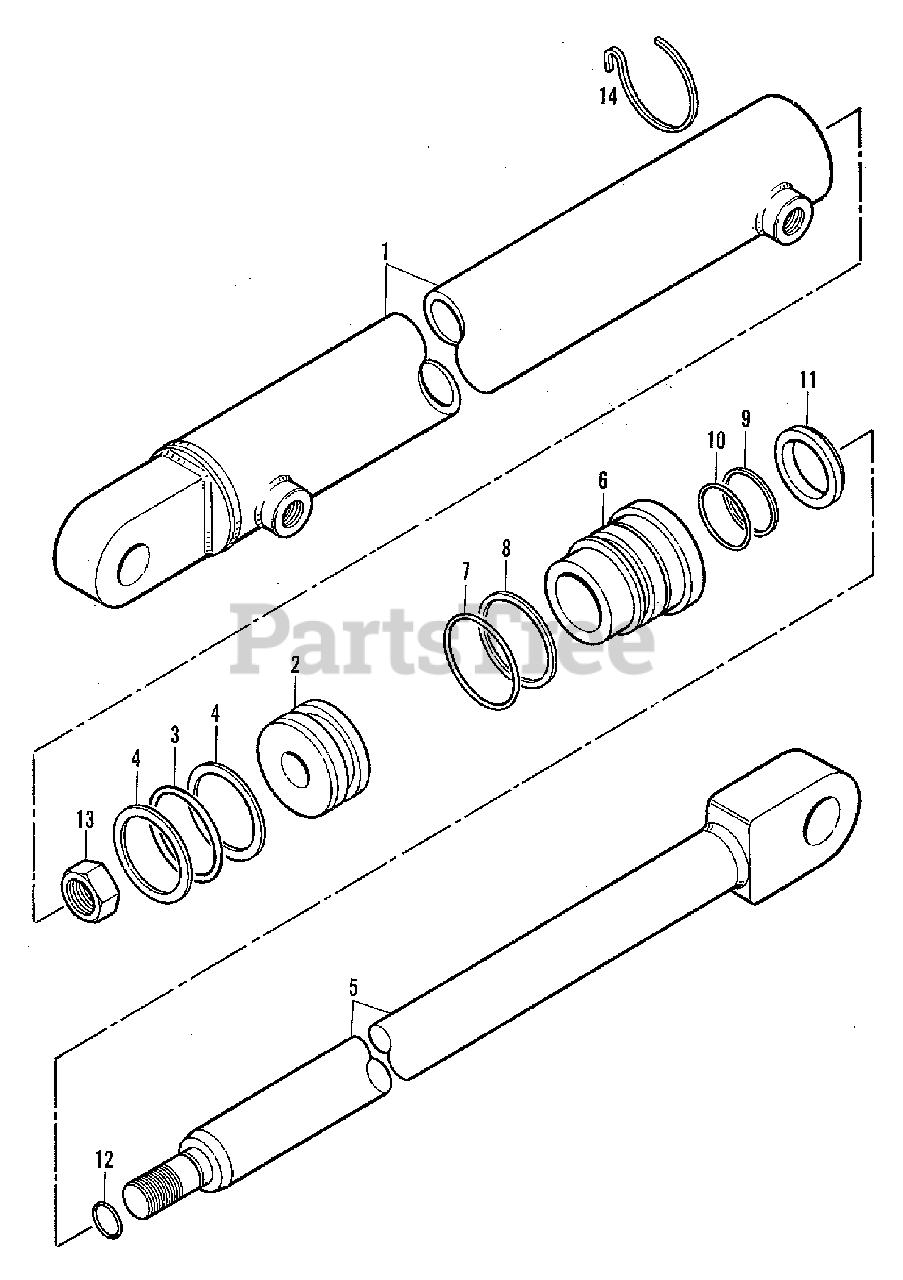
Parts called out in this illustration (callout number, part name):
1	TUBE ASSEMBLY
3	O-RING, Piston
4	WASHER, Backup, Large
5	Rod, Piston
7	O-RING, Static
8	WASHER, Backup, Static
9	WASHER, Backup, Rod
10	O-RING, Rod
11	WIPER, Rod
12	O-RING, Piston Rod
13	NUT, Lock, Piston Rod
14	RING, Retaining, Head
